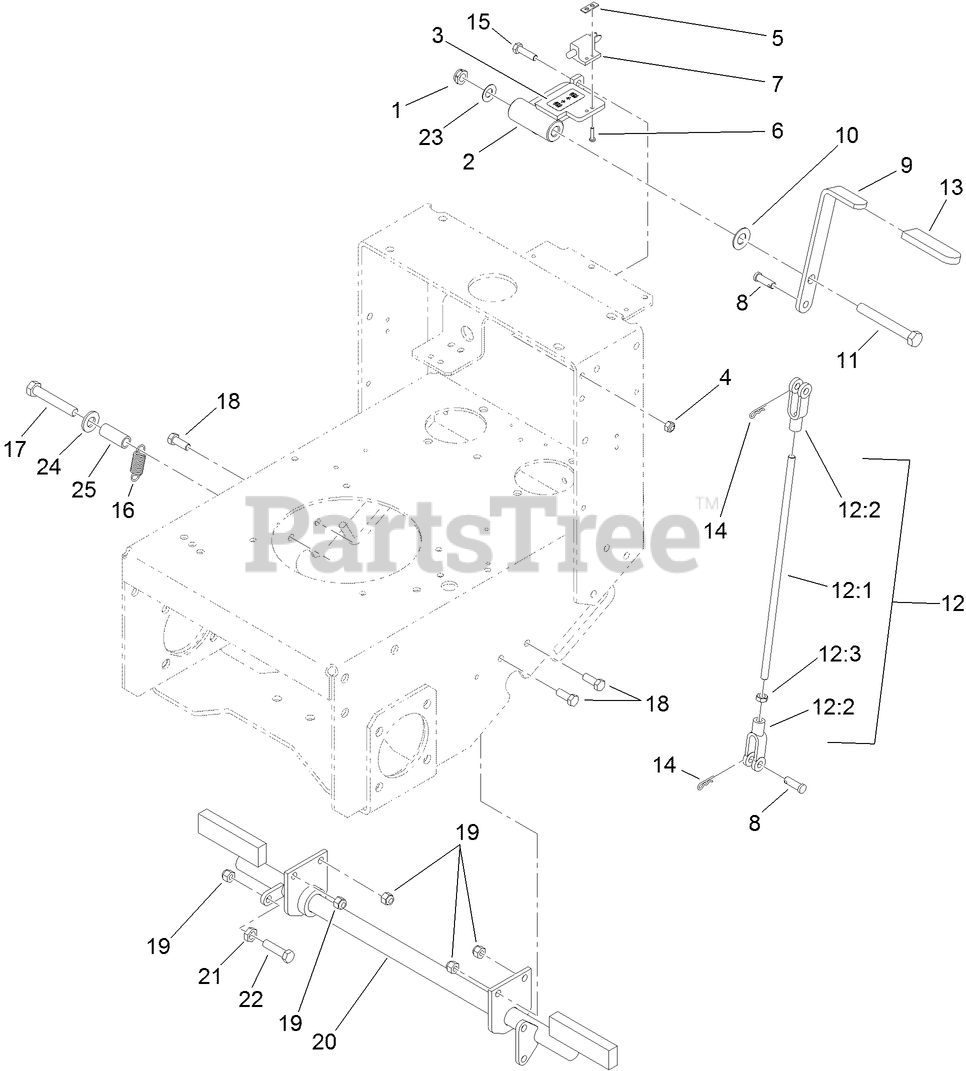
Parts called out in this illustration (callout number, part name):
1	NUT-LOCK, NI
2	SUPPORT-HANDLE
3	DECAL-BRAKE
4	NUT-LOCK, NI
5	PLATE-TAPPED
6	SCREW-HWH
7	SWITCH-CLOSED, NORMALLY
8	PIN-CLEVIS
9	HANDLE-BRAKE
10	BEARING-THRUST
11	SCREW-HH
12	BRAKE ROD ASM
12:1	ROD-BRAKE
12:2	YOKE-LINKAGE, BRAKE
12:3	NUT-HEX
13	GRIP-LEVER
14	PIN-COTTER
15	SCREW-HH
16	SPRING-BRAKE
17	SCREW-HH
18	SCREW-HH
19	NUT-LOCK, NI
20	SHAFT-BRAKE, PARKING
21	NUT-JAM
22	SCREW-HH
23	WASHER-SPRING, CONICAL
24	WASHER-FLAT
25	SPACER-SPRING
